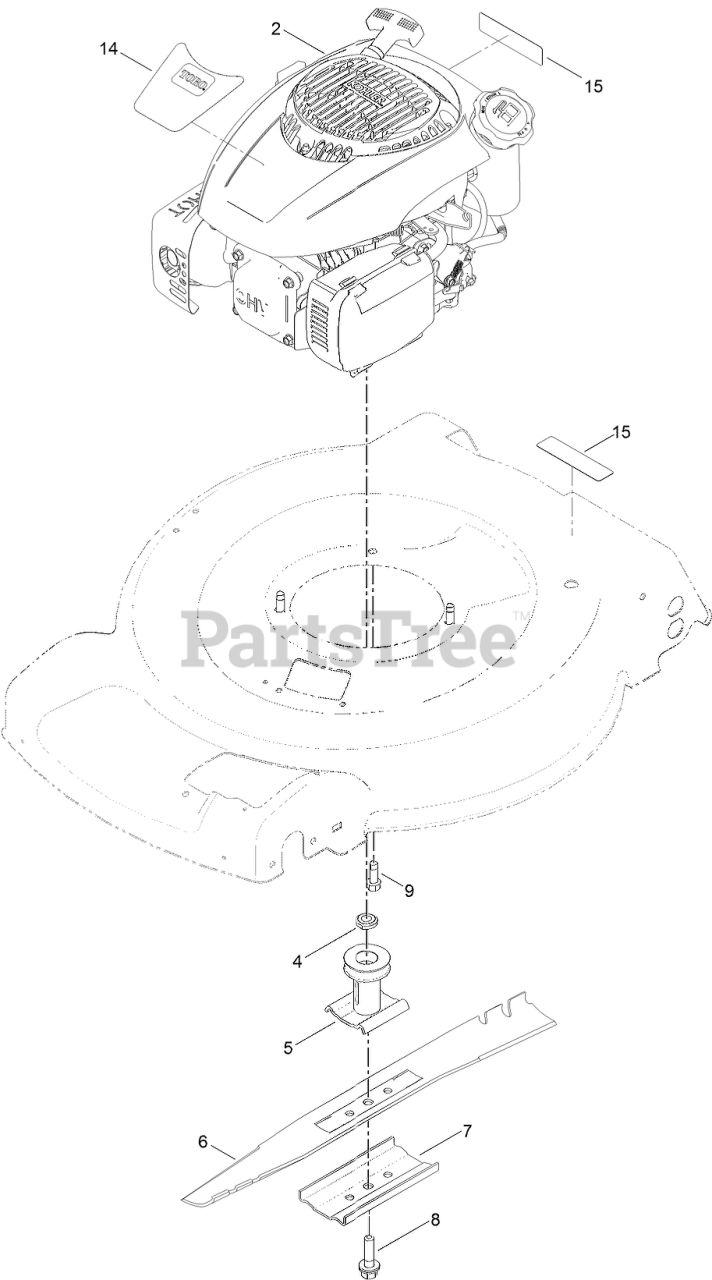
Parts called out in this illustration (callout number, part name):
4	SPACER-DRIVER
5	DRIVER-BLADE
6	BLADE-22 INCH
7	SUPPORT-BLADE
8	BOLT-BLADE
9	SCREW-TAPTITE
14	DECAL-SHROUD
15	DECAL-ARRESTER, SPARK
